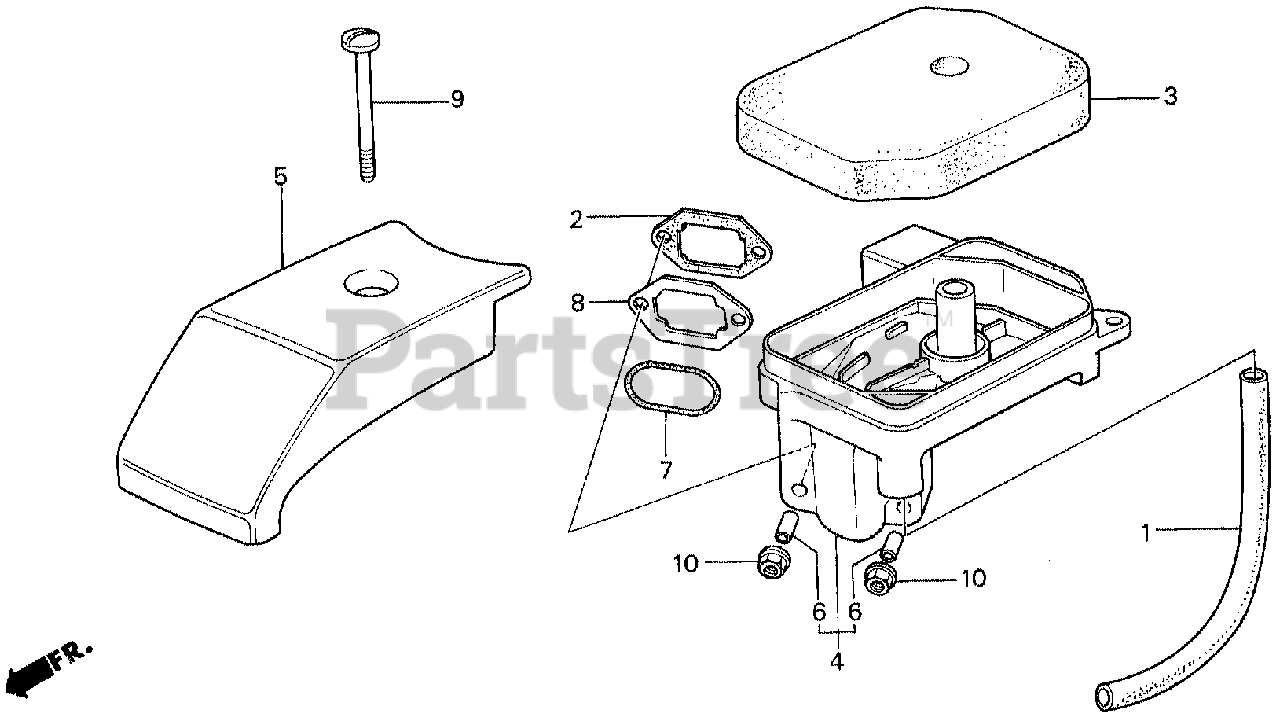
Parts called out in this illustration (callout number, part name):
1	TUBE, BREATHER (NOT AVAILABLE)
2	GASKET, AIR CLEANER
3	ELEMENT, AIR CLEANER
4	HOUSING, AIR CLEANER
5	COVER, AIR CLEANER (NOT AVAILABLE)
6	COLLAR, AIR CLEANER HOUSING (NOT AVAILABLE)
7	O-RING, MUFFLER (NOT AVAILABLE)
8	BRACKET, FAN COVER
9	BOLT, AIR CLEANER COVER
10	NUT, FLANGE (5MM)
